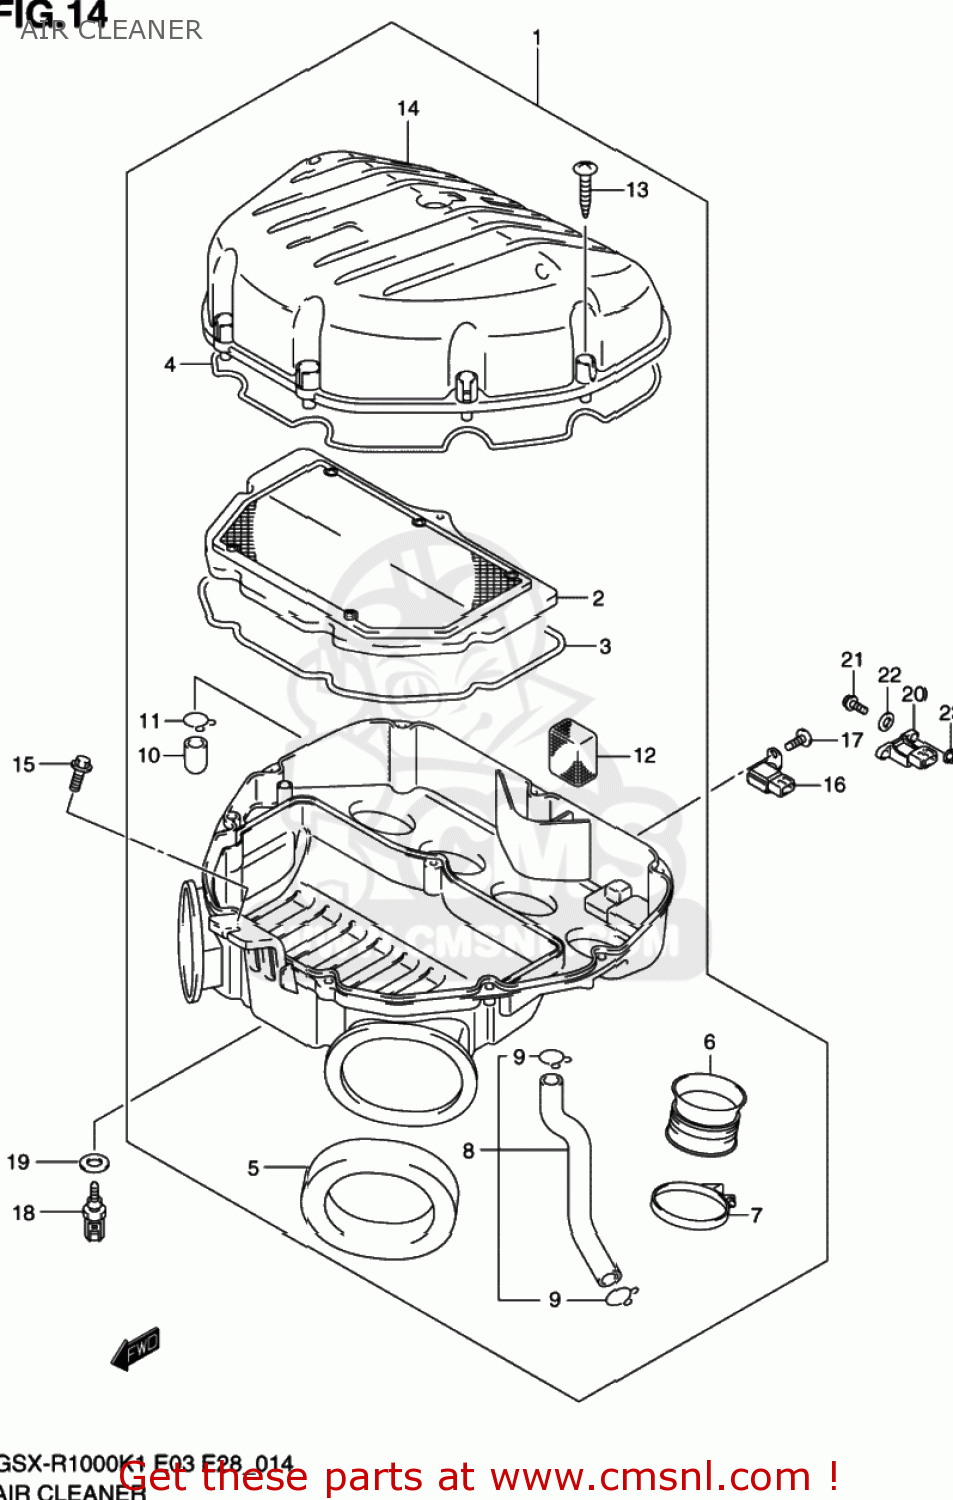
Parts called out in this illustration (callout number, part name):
1	CLEANER ASSY,AIR
2	FILTER ASSY,AIR CLEANER
3	GASKET,CASE (NAS)
4	GASKET,CAP (NAS)
5	CUSHION,DUCT
6	TUBE,OUTLET
7	CLAMP
8	TUBE,BREATHER
9	CLIP
10	PLUG
11	CLIP
12	FILTER,BREATHER
13	SCREW
14	CAP,AIR CLEANER
15	BOLT(6X16)
16	SENSOR,BOOST
17	SCREW 6X10
18	SENSOR,WATER TEMP
19	GASKET(12X17X1) (NAS)
20	SENSOR,BOOST
21	BOLT,OIL FILLE
22	WASHER(6.5X20X1.2)
23	NUT
